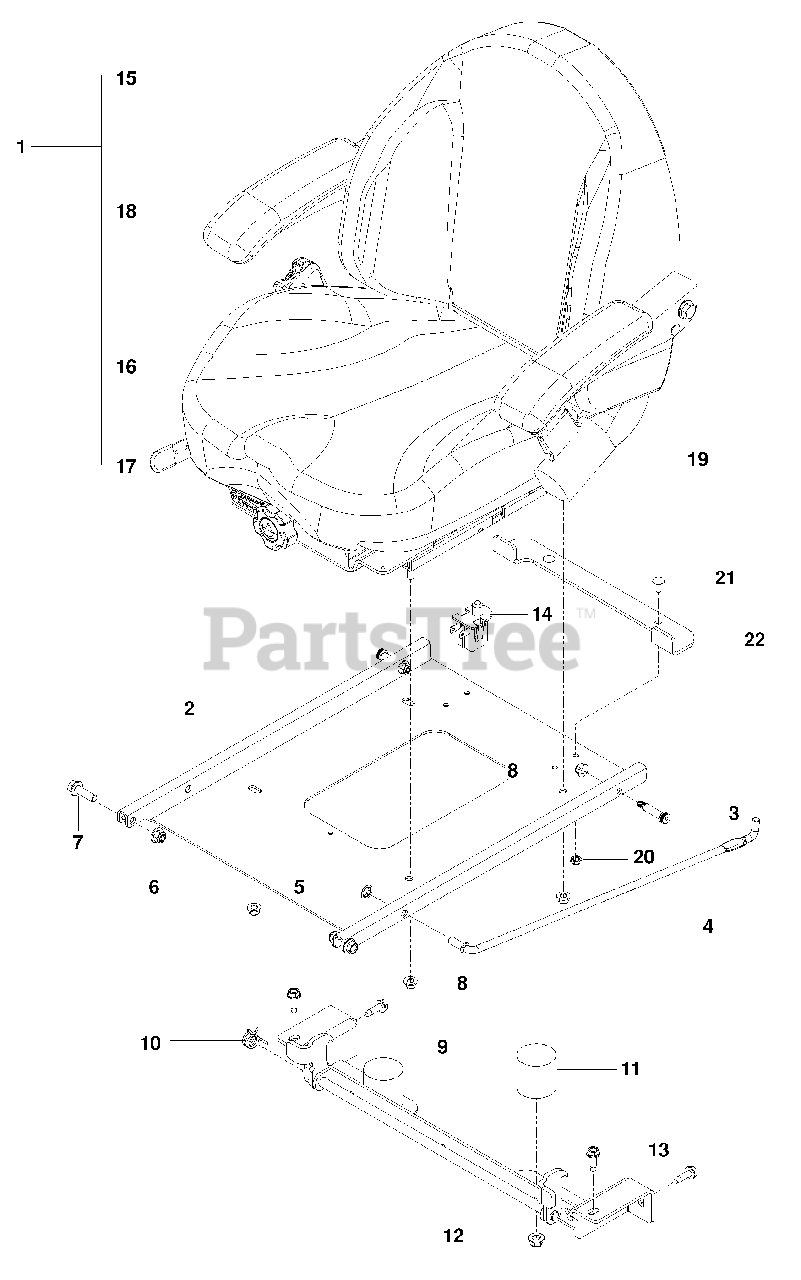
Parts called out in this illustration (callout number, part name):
1	Seat Assy
2	Pan, Seat Blk
3	Bolt 3/8 X 1 1/4 5/16-18 Shldr
4	Rod, Seat
5	Retainer Nut 3/8
6	Nut 3/8-16 Hex Flg Nyloc
7	Hhfs 3/8-16 X 1 1/4
8	Nut 5/16-18 Hex Flange Nyloc
9	Latch, Seat
10	Spring, Torsion
11	Bumper, Rubber
12	Nut 3/8-16 Hex Flg Nyloc
13	Bolt 5/16-18 X 1 Thd Frm
14	Switch, Seat
15	Cover, Back
16	Cover Kit, Cushion
18	Armrest, Lt
19	Seat Belt
20	Nut 1/4-20 Hex Thin Nyloc
21	Rhssnb 1/4-20 X 5/8
22	Stop, Seat Blk
